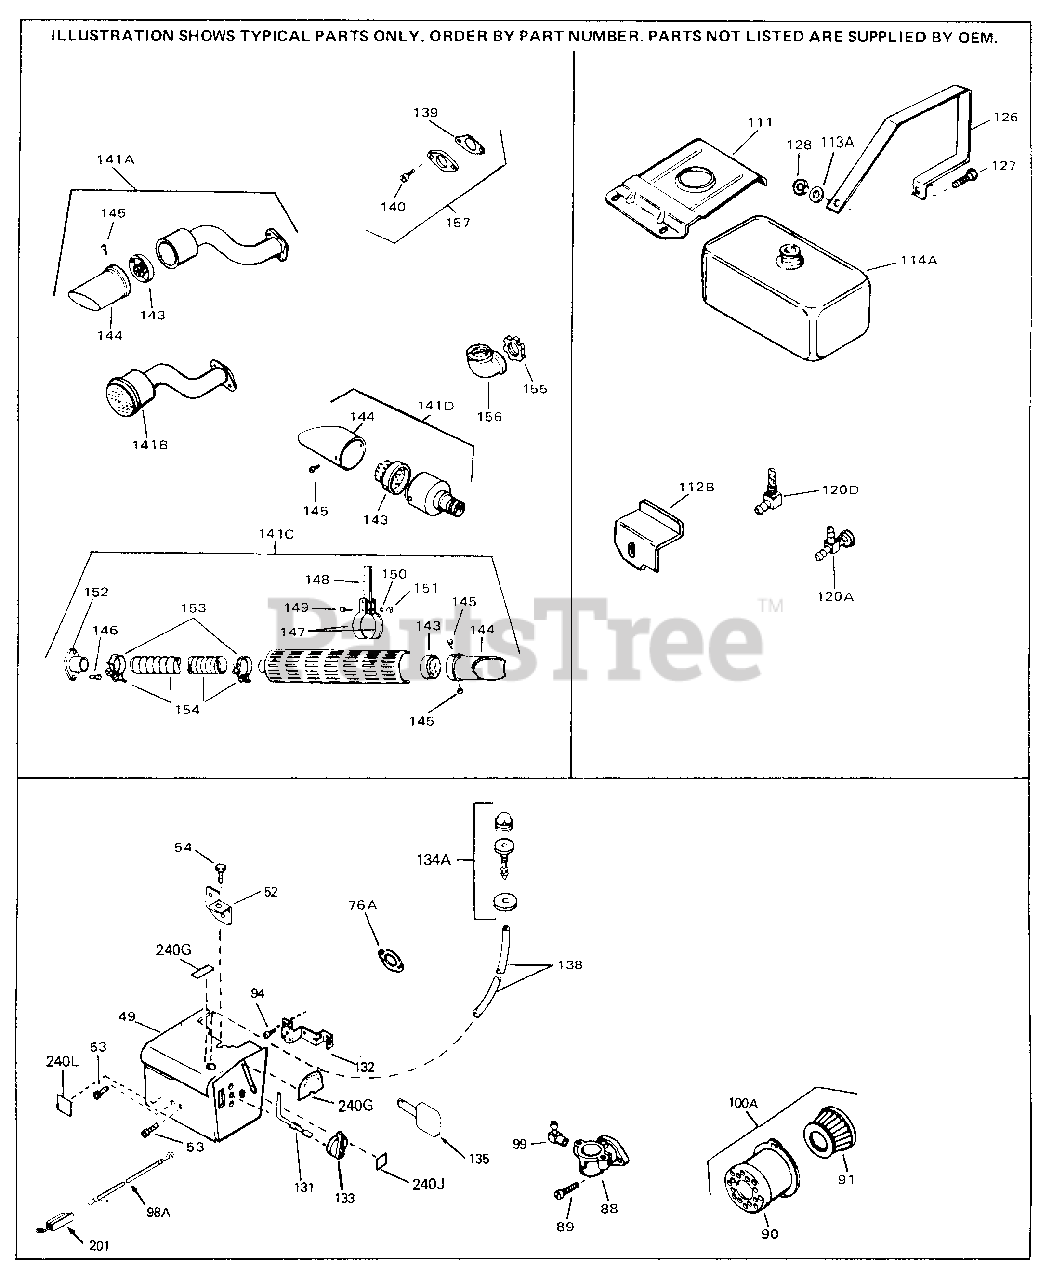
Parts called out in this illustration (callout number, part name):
90	Body, Air cleaner
91	Air Filter (Paper) also available in Packaged Part #740029B
94	Screw, 10-32 x 1/2"
100A	Air Cleaner Ass'y. (Incl. 76, 90, 91, 92, 93, 94, & 221B) (Use as required )
111	Fuel Tank Bracket
140	Screw, T-30, 1/4-20 x 1/2"
141D	Muffler (Incl. 143, 144 & 145) (This spark arrester mufflercan be used on any model.)
155	Nut, Conduit
156	Elbow, Street 90-degree
157	Muff.Adapter Kit (Incl. 139,140) As r equired
201	Terminal Assy. (Use as required)
